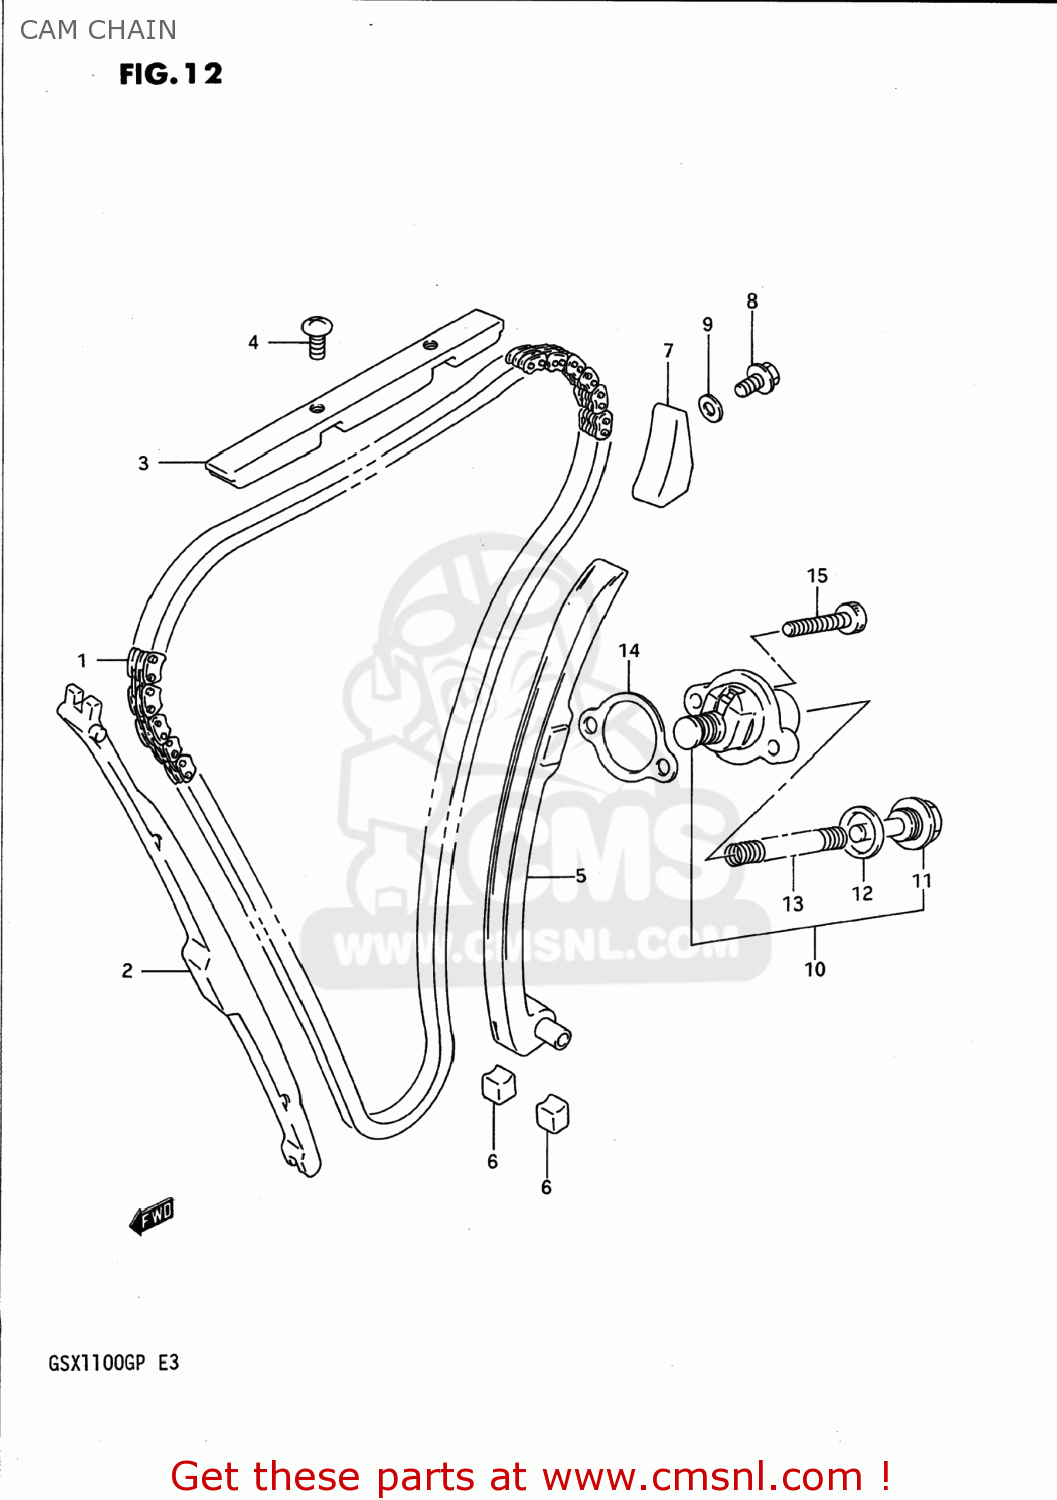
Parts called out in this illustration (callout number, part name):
1	CHAIN,CAMSHAFT DRIVE
2	GUIDE,CAM CHAIN NO.1
3	GUIDE,RR CAM CHAIN NO.1
4	SCREW
5	TENSIONER,CAM CHAIN
6	CUSHION,CAM CHAIN TENSIONER
7	GUIDE,CAM CHAIN NO.2
8	BOLT
9	GASKET(5.8X13X1.2) (NAS)
10	ADJUSTER ASSEMBLY,TENSIONER
11	PLUG
12	GASKET (NAS)
13	SPRING
14	GASKET,TENSIONER ADJUSTER (NAS)
15	BOLT
